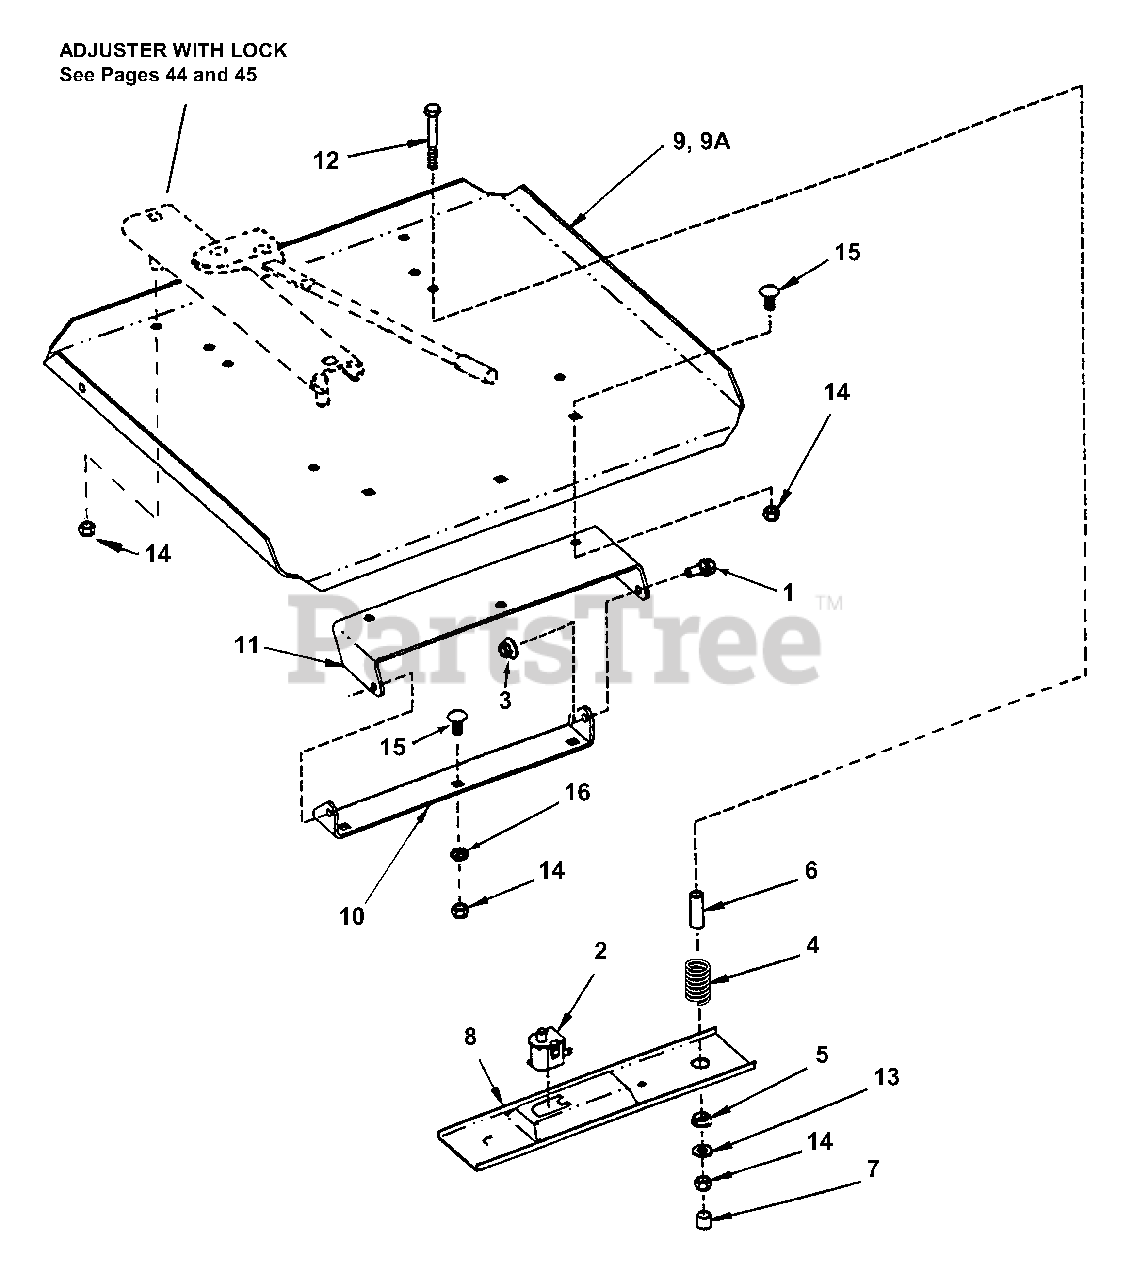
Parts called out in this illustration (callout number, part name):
1	BOLT, 5/16-18 x 3/4" Shoulder
2	SWITCH, Seat (Normally Closed)
3	NUT, 5/16-18 Hex Flange Lock
4	SPRING
5	BUSHING, Molded Seat, 1/2 I.D. x 5/8" O.D.
6	SPACER, 5/16 I.D. x 1-3/8" Long
7	CAP, Vinyl
8	HOLDER, Seat Switch
9	PLATE, Seat Support
9A	PLATE, Seat Support (Models MZM2200K & MZM2300K Only)
10	HINGE, Seat Support
11	BRACKET, Upper Seat Support Hinge
12	BOLT, 5/16-18 X 2-1/2" GD5 YZ
13	WASHER, 5/16 x 11/16 O.D. Flat
14	NUT, 5/16-18 HEX NYLON LOCK
15	BOLT, 5/16-18 x 3/4 Carriage Grade 5
16	RETAINER, 5/16" Bolt
